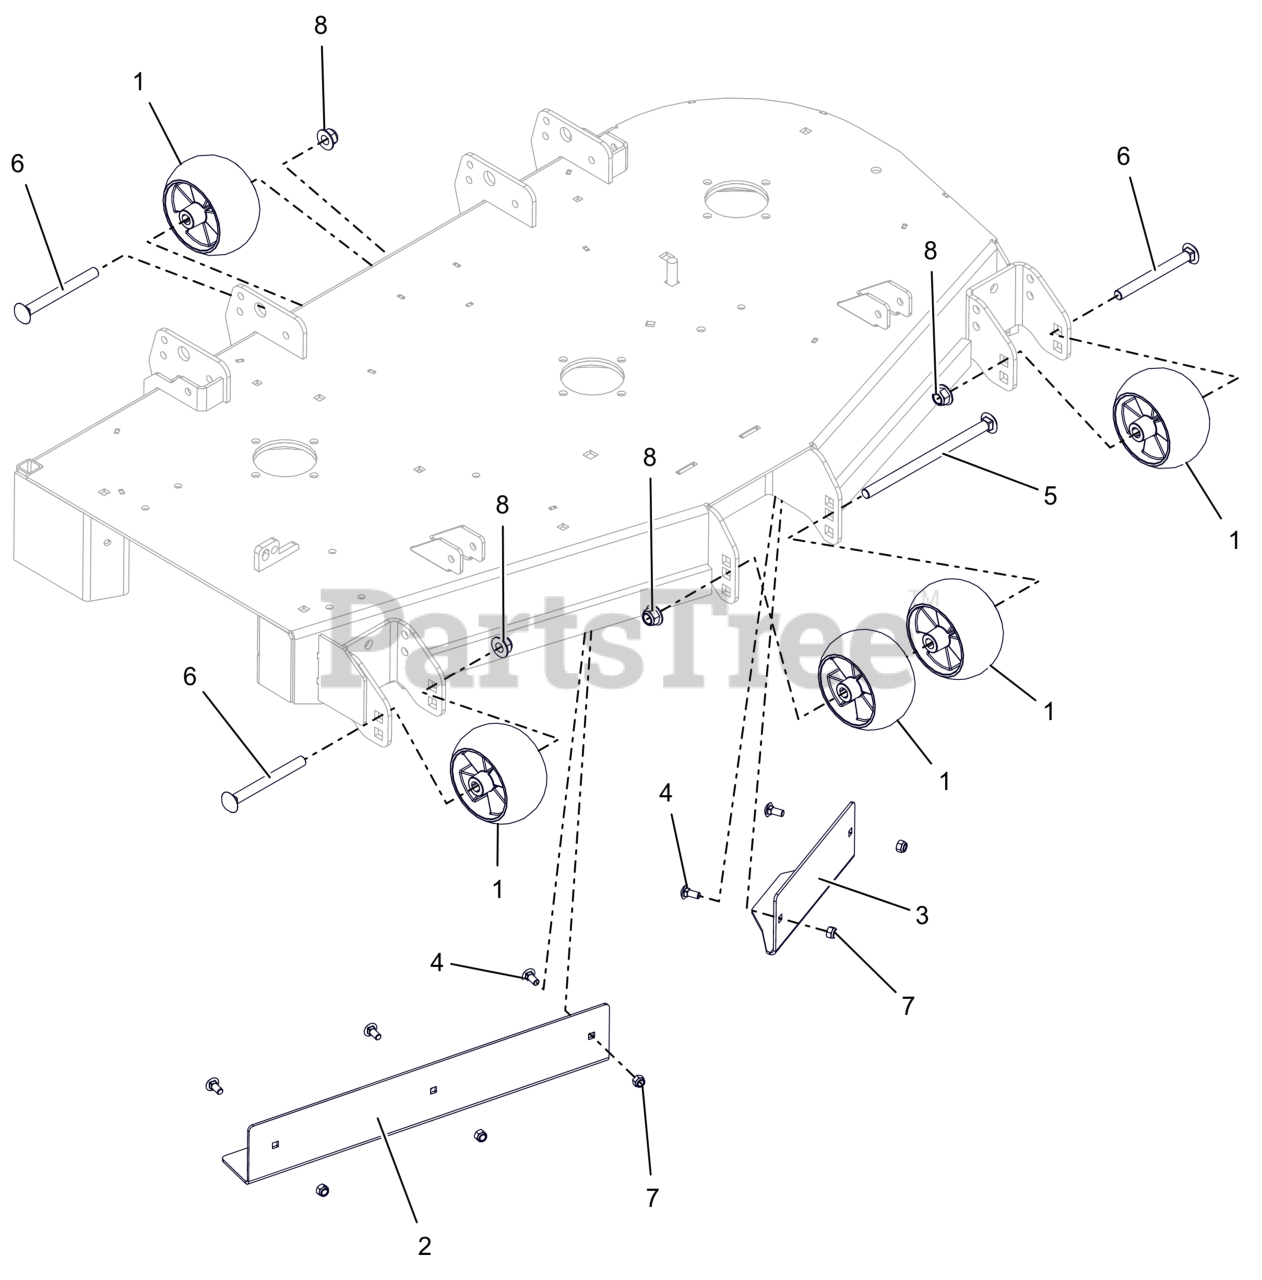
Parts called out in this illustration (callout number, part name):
1	WHEEL, ANTI SCALP - 5X3 CTR W/RIBS
2	BAFFLE, 48" RH VACUUM (RED)
3	BAFFLE, 44/48" LH VACUUM (RED)
4	BLT,RHSN .31-18X.75 G5 ZCC
5	BTL,RHSN .500-13 X 8.5S G5 ZCC
6	BLT, RHSN .50-13X5.00 G5 ZCC
7	NUT,NYL .31-18 G5 ZCC
8	NUT,NYL-FLG .50-13 GF ZCC
